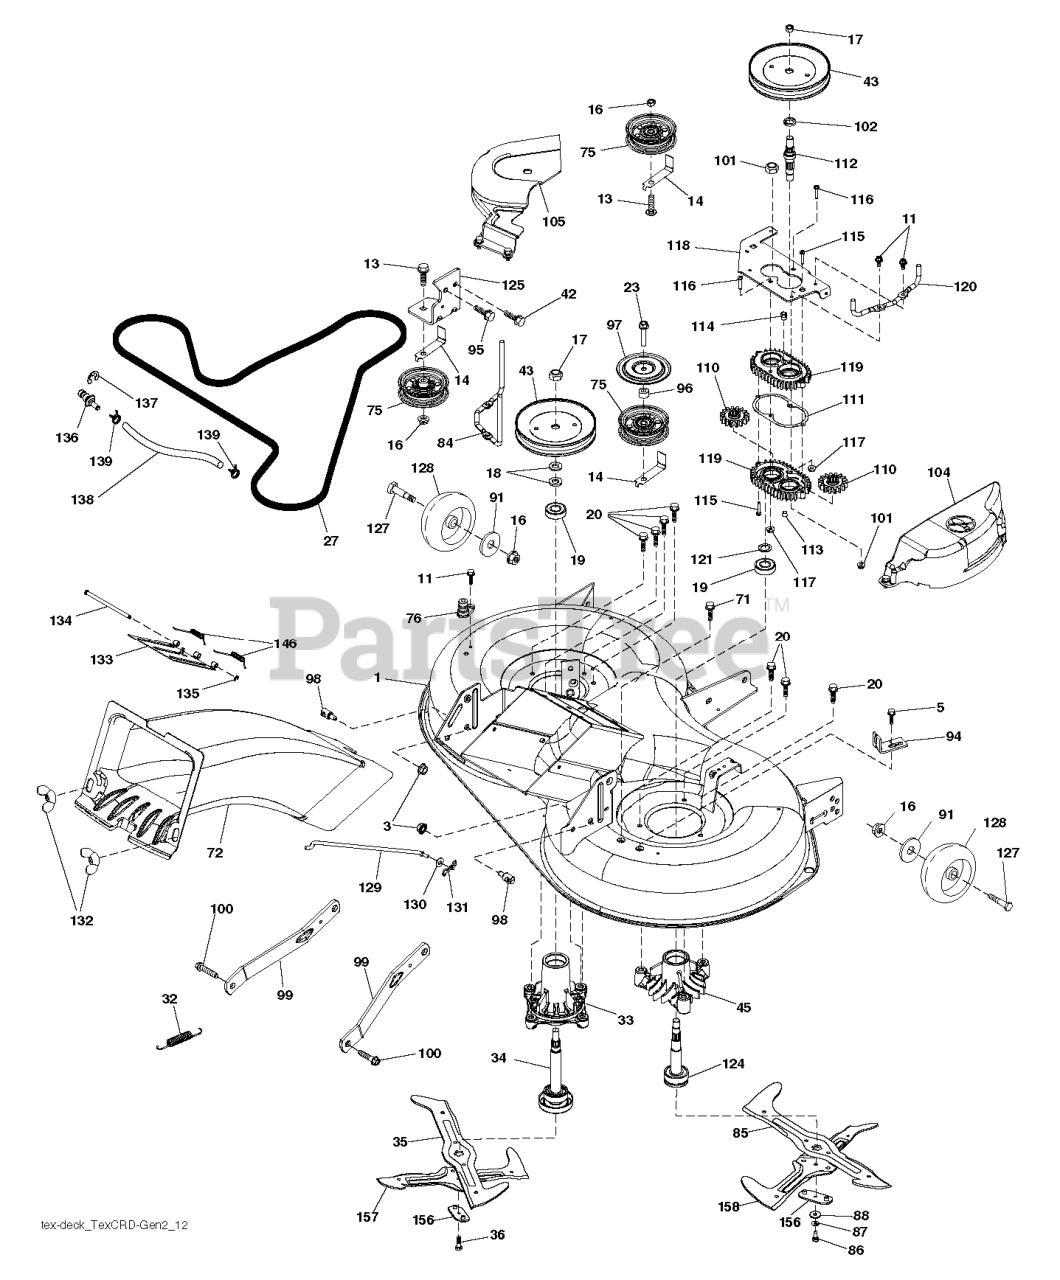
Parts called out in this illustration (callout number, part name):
3	NUT LOCK HEX FLANGE 5/16-18
5	BOLT.5/16HEX.WHS.HD
11	SCREW.1/4-20X5/8
13	BOLT.3/8-16X1.50
14	KEEPER, BELT IDLER
16	NUT LOCK FLG 3/8-16 UNC
17	NUT.FLANGE.LOCK.TOP
18	WASHER.SPACER.MANDREL
20	SCREW, WASHER HEAD
23	SCREW LT
27	BELT BELT. ELECTRIC MOWER DRIV
32	SPRING 107CM & 97CM ELECTRIC D
33	RP.HOUSING.MANDREL.4PT.
34	SHAFT.ASM.MDRL.N/GREASE.38
35	BLADE.3N1.LH.CRD
36	BOLT.WASHER.ASM.7/16-2
42	SCREW
43	PULLEY PULLEY MANDREL 5.438 PD
45	HOUSING.MANDREL.44/46" VENT
71	SCREW 3/8-16X1/2
72	RP.97/107.TEX.CRD.UPPER CHUTE
75	FLAT IDLER PULLEY
76	PORT.WASHOUT
84	KEEPER KEEPER. LH MANDREL BELT
85	BLADE.3N1.RH.CRD
86	BOLT.3/8-24X1.25GR8. LHTHRD
87	LOCKWASHER
88	WASHER.BLADE
91	WASHER
94	BRKT.CLUTCH.CABLE
95	SCREW, 3/8-16X3/4
96	SPACER
97	PROTECTOR
98	STUD.FASTNER.W/ANTI-ROTATE
99	ARM.SUSPENSION.MOWER.R
100	BOLT.SHOULDER
101	NUT.CROWNLOCK.9/16 -18.UNC
102	SPACER BEARING
110	CRD.SPUR.GEAR
111	GASKET GASKET GEARCASE
112	SHAFT SHAFT. CRD GEARCASE ADAP
113	PLUG PLUG OIL
114	VALVE VALVE RELIEF
115	SCREW
116	BOLT.CARIGE.SS.1/4-20X1.75GR5
117	NUT T
118	ARM ARM. CLUTCHING 107 TEX CRD
119	GEARCASE GEARCASE SUBASM
120	KEEPER KEEPER. RH MANDREL BELT
121	WASHER WASHER
124	MANDREL SHAFT NON/GREASE
125	BRACKET BRACKET IDLER CHASSES
127	BOLT.SHOULDER.3/8-16X3-5/8.
128	RP WHEEL. GUAGE RALLY
129	ROD ROD. SWAY CRD GEN II
130	WASHER
131	PIN.COTTER.5/16.BOW TI
132	KNOB.HANDLE.3/8.TRI-POINT.BLAC
133	COVER DOOR.107 CM CRD EZ MULCH
134	PIN PIN.HINGE
135	E-RING.5/16"
136	PLUG WASHOUT PORT HOOKUP
138	107.WASHOUT.PORT.HOSE (2 2)
139	HOSE.3/8.CLAMP (2 2)
146	SPRING SPRING: EZ MULCH DOOR
156	ADAPTER ADAPTER.CROSSBLADE.107
157	BLADE 107CM.CROSS.BLADE
158	BLADE.CROSS.RH.CRD.107
